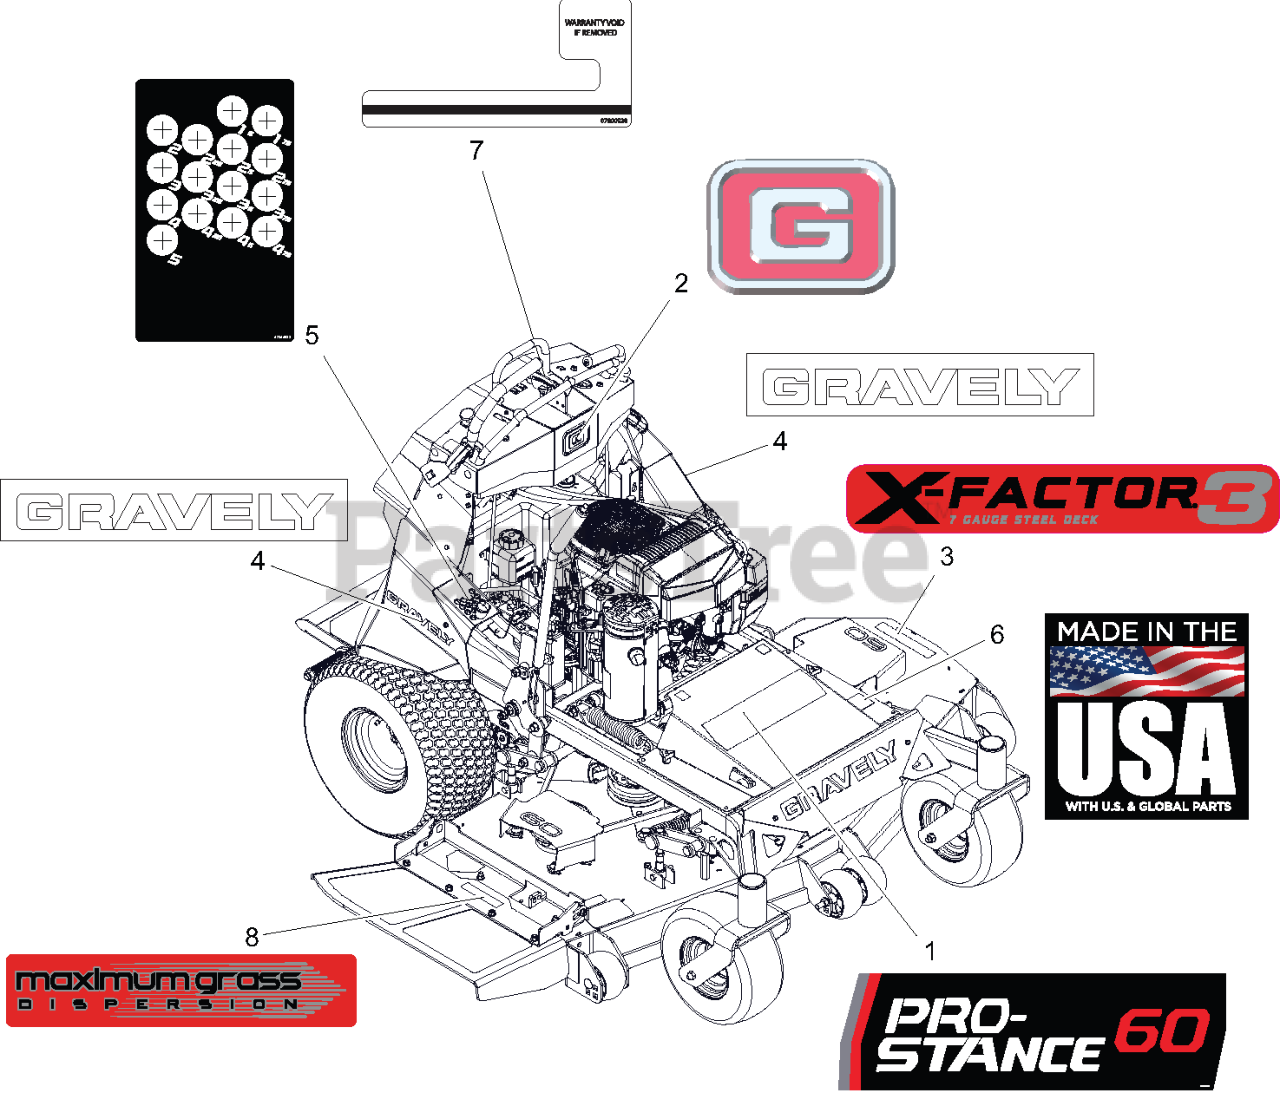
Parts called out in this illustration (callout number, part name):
1	DECAL, PROSTANCE 60
2	DECAL, GRAVELY BRAND
3	DECAL, DECK - X-FACTOR 3
4	DECAL, 9.5" GRAVELY LOGO
5	DECAL, DECK - HEIGHT ADJUST
6	DECAL, MADE IN USA
7	DECAL,HOURMETER - SECURITY
8	DECAL, DECK - MAX GRASS
